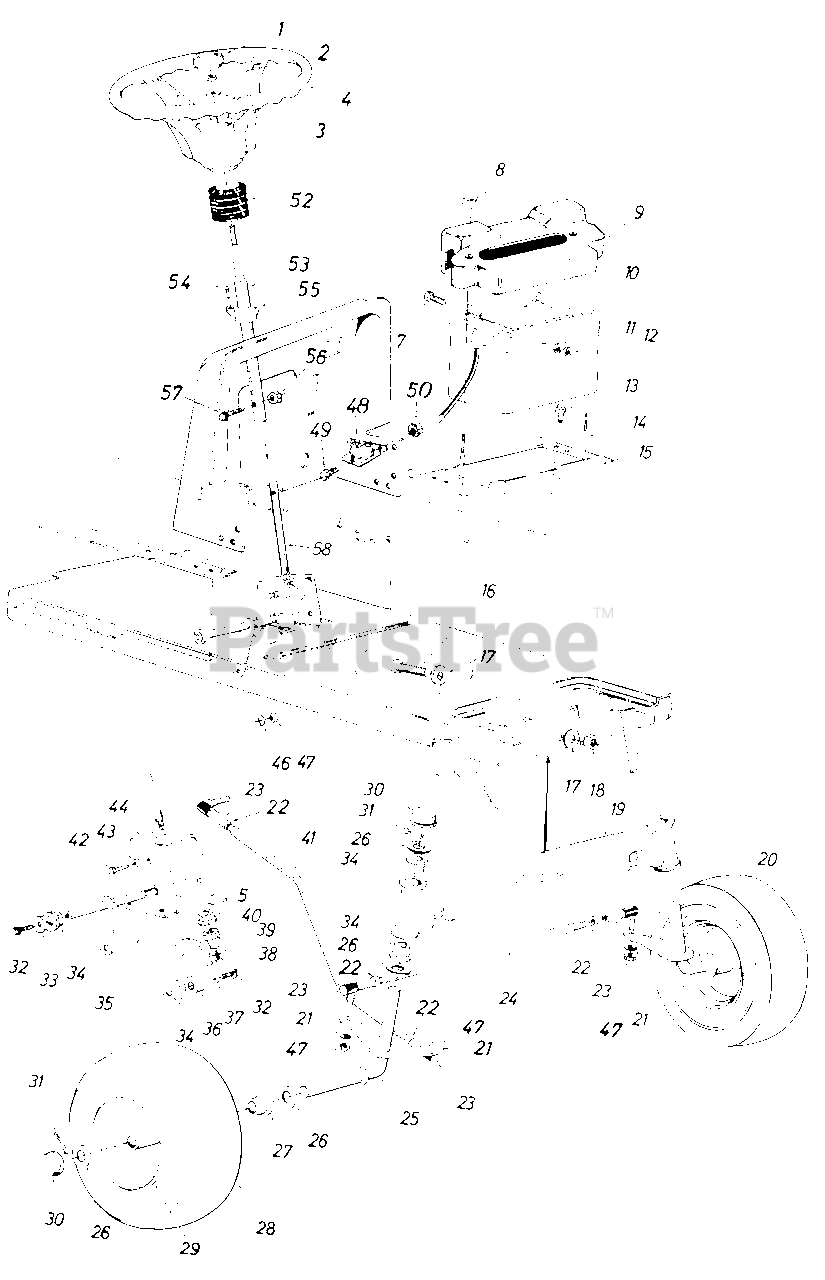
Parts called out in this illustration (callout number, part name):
1	Steering Wheel Cap
2	Hex Cent. L-Nut 5/16-18 Thd.
3	Bell-Wash. 5/16" I.D. x .87" O.D. x .060
4	Steering Wheel
7	Hex Scr. 1/4-20 x .62" Lg.
8	Wing Nut Plastic 1/4-20 Thd.
9	Battery Cover
10	12-V Battery
11	L-Wash. 1/4" Scr.
12	Hex Nut 1/4-20 Thd.
13	Hex Thd. Rolling Scr. 1/4-20 x.50" Lg.
14	Battery Hold Down Rod
15	Battery Plate
16	Hex Scr. 5/8-18 x 2.50" Lg.
17	Flat Wash. .66" I.D. x 2.25" O.D. x .17
18	Hex Cent. L-Nut 5/8-18 Thd.
19	Front Pivot Bar Ass'y.
20	Front Axle Ass'y. L.H.
21	L-Wash. 3/8" Scr.
22	Hex Jam Nut 3/8-24 Thd.
23	Ball Joint Ass'y.
24	Tie Rod
25	Front Axle Ass'y. R.H.
26	Fl-Wash. .780 I.D. x 1.59 O.D.
27	Flange Bearing
28	Front Wheel Ass'y. Comp.
29	Front Wheel Rim Only
30	Dust Cover
31	Cotter Pin 5132" Dia. x 1.00" Lg.
32	Hex Scr. 3/8-24 x .75" Lg. Grade 5
33	Fl-Wash. 3/8 I.D. x 1.25 O.D. x .090
34	Flange Double "D" Brg. .753 I.D.
35	Steering Arm Shaft Ass'y.
36	Side Gear Steering
37	Bell-Wash. 3/8" I.D.
38	Hex Cent. L-Nut 5/16-24 Thd.
39	Fl-Wash. 5/16" I.D. x .62 O.D. x .059
40	Pinion Gear Steering
41	Drag Link
42	Hex Nylon Scr. 3/8-16 x 1.25" Lg.
43	Hex Nut 3/8-16 Thd.
44	Steering Gear Sup. Ass'y.
46	L-Wash. 3/8" Scr.
47	Hex Nut 3/8-24 Thd.
48	Solenoid
49	Hex Bolt 1/4-20 x .50" Lg.
50	Hex Sems Nut 1/4-20 Thd.
52	Steering Bellow
53	Upper Steering Shaft
54	Oval Hd. Cr.-Sunk Scr. #10 x 5/8" Lg.
55	Fl-Bearing .89" I.D. x 1.36" O.D.
56	Hex L-Nut 1/4-20 Thd.
57	Hex Bolt 1/4-20 x 1.31" Lg.
58	Lower Steering Shaft
